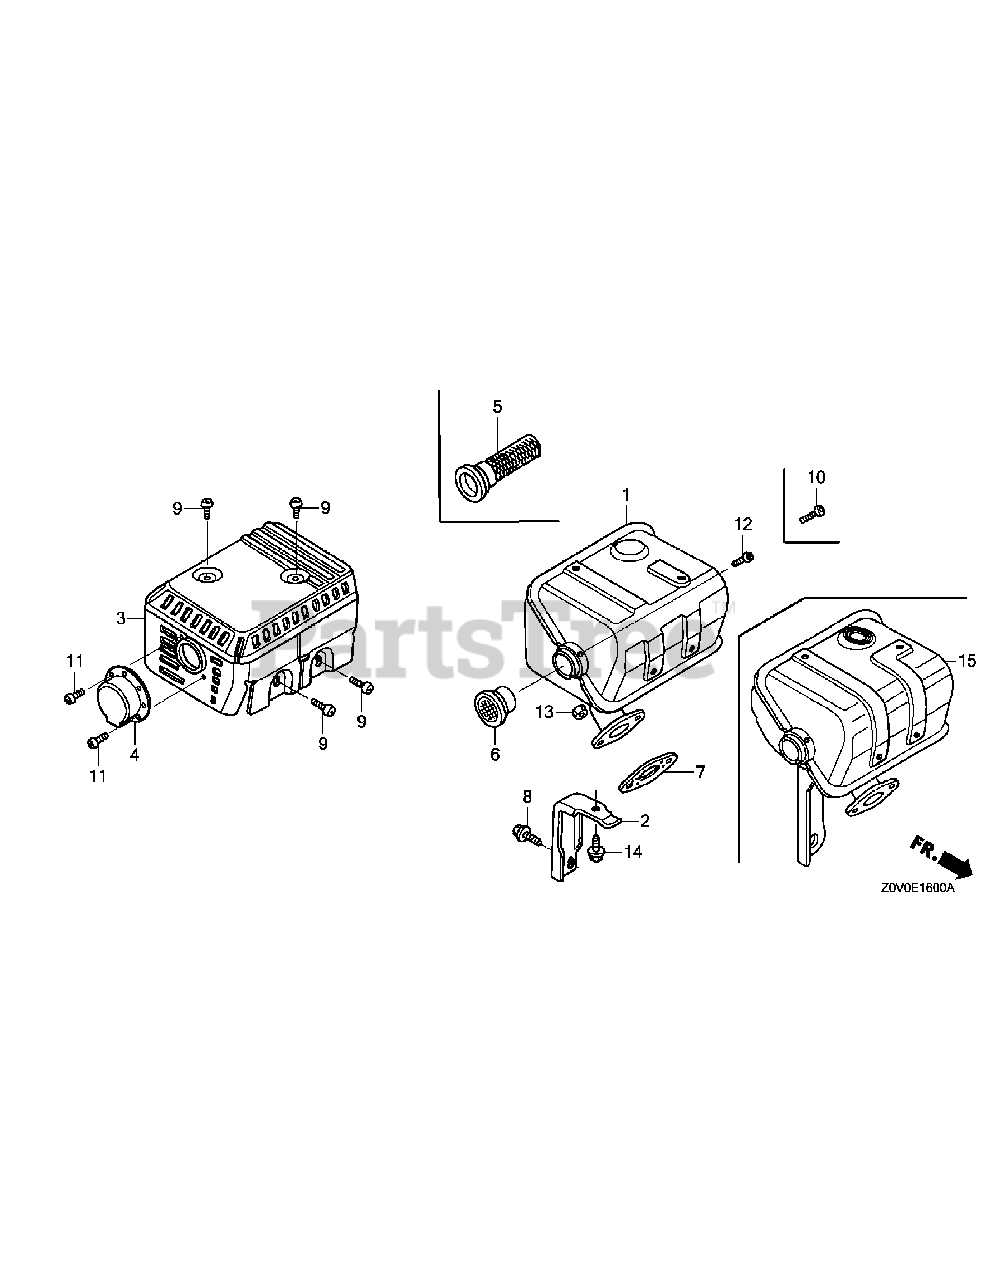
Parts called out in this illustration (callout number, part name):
1	Muffler Comp.
2	Stay, Muffler
3	Protector Comp., Muffler
4	Cap, Muffler
5	Arrester, Spark
6	Netting, Wire Flange
7	Gasket, Muffler
8	Bolt, Flange, 6X13(Ct200)
9	Screw, Tapping, 5X8
10	Screw, Tapping, 4X6
11	Screw, Tapping, 4X6
12	Screw, Tapping, 4X6
13	Nut, Hex., 8Mm
14	Bolt, Flange, 6X12
15	Muffler Comp.
